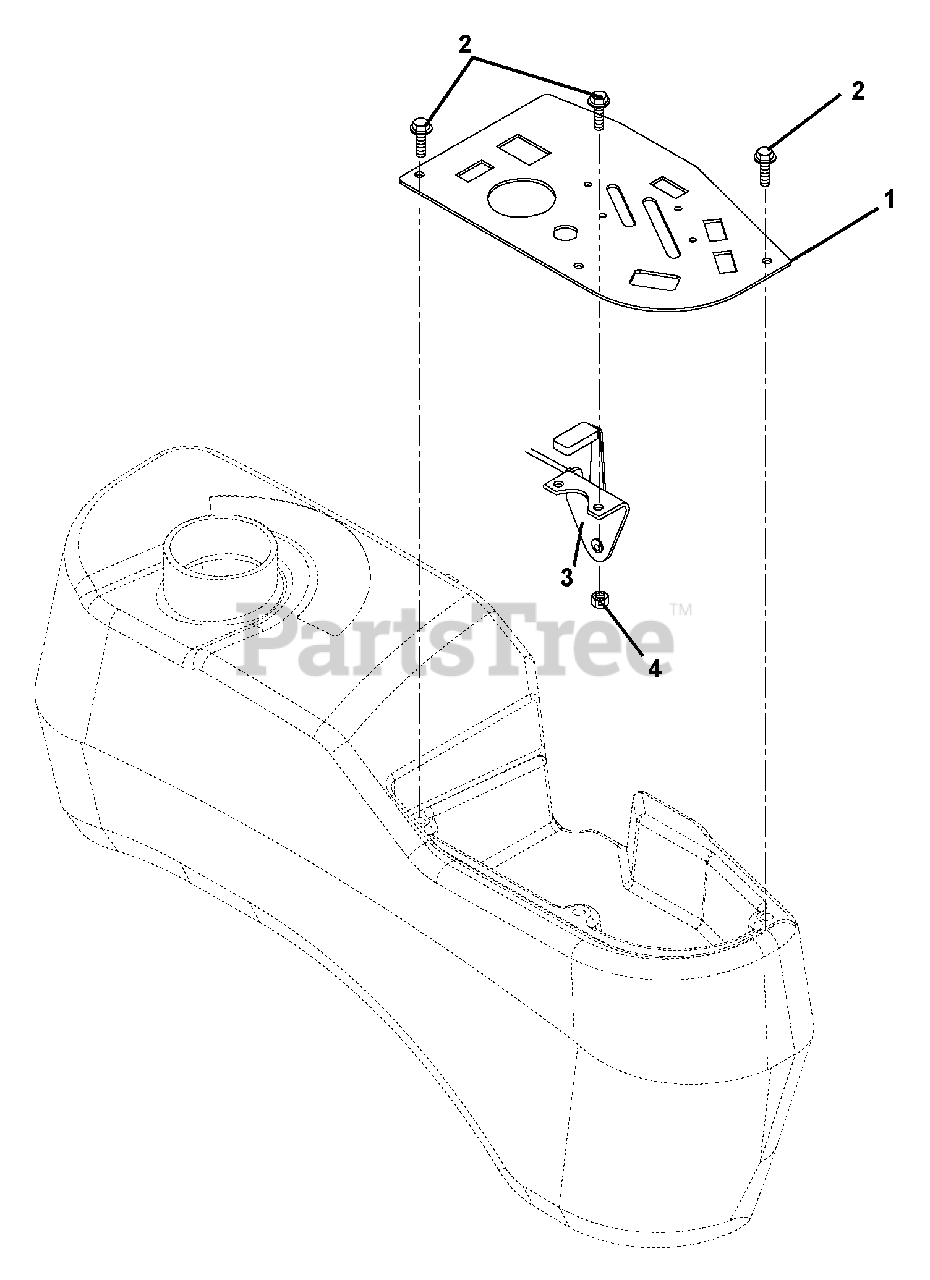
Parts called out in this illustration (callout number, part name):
1	Panel-Control
2	Screw-Machine 10-24 x .50 Hex Washer Head
3	Throttle, Control
4	Nut-Locking-Nylon 10-24 With Insert
